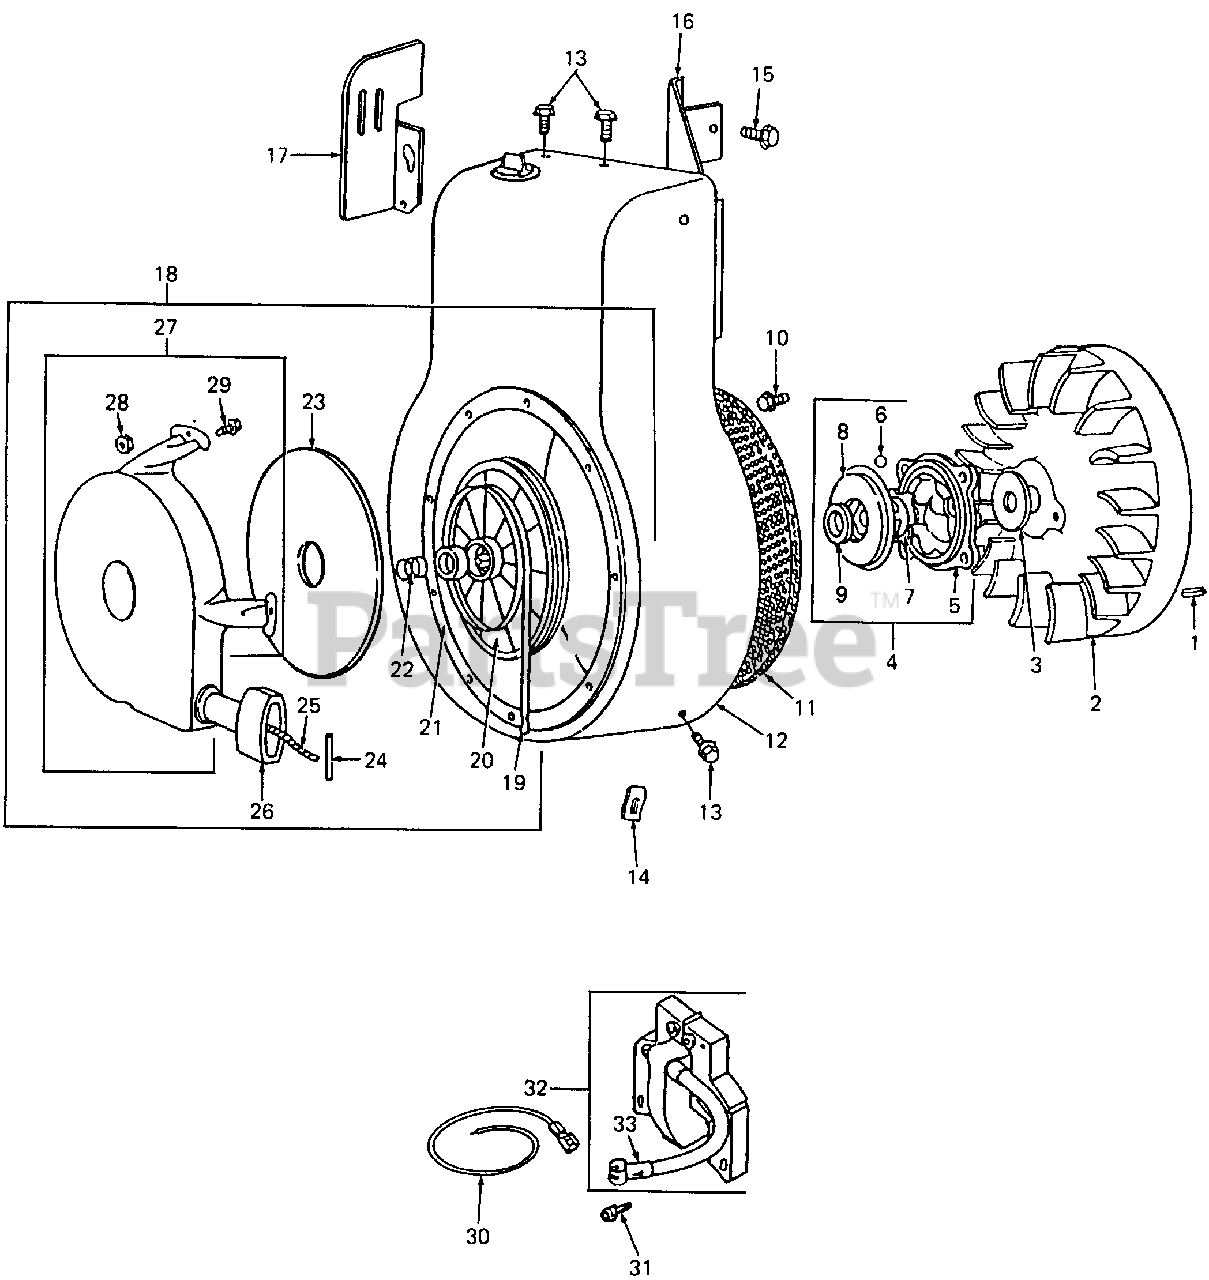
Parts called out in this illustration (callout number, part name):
1	Key, Flywheel
3	Washer, Spring
4	Clutch Assy, Starter
5	Housing, Starter Clutch
6	Ball, Clutch
7	Ratchet, Starter Clutch
8	Washer, Retainer
9	Washer, Ratchet Sealing
10	Screw, Sem
11	Screen, Starter
12	Housing, Blower
13	Screw, Sem
14	Anchor, Spring
15	Screw, Sem
16	Guard, Flywheel
17	Guide, Air
18	Starter Assy
19	Spring, Starter
20	Pulley, Starter
21	Adapter, Ratchet Spring
22	Spring, Ratchet
24	Pin, Starter Rope
25	Rope, Starter, 63" Lg
26	Grip, Starter Rope
27	Housing, Starter
28	Nut, Hex
29	Screw, Sem Starter Housing Mtg
30	Wire, Ground
31	Screw, Sem, Armature Mtg
32	Armature, Magneto
33	Terminal, Ignition Cable
